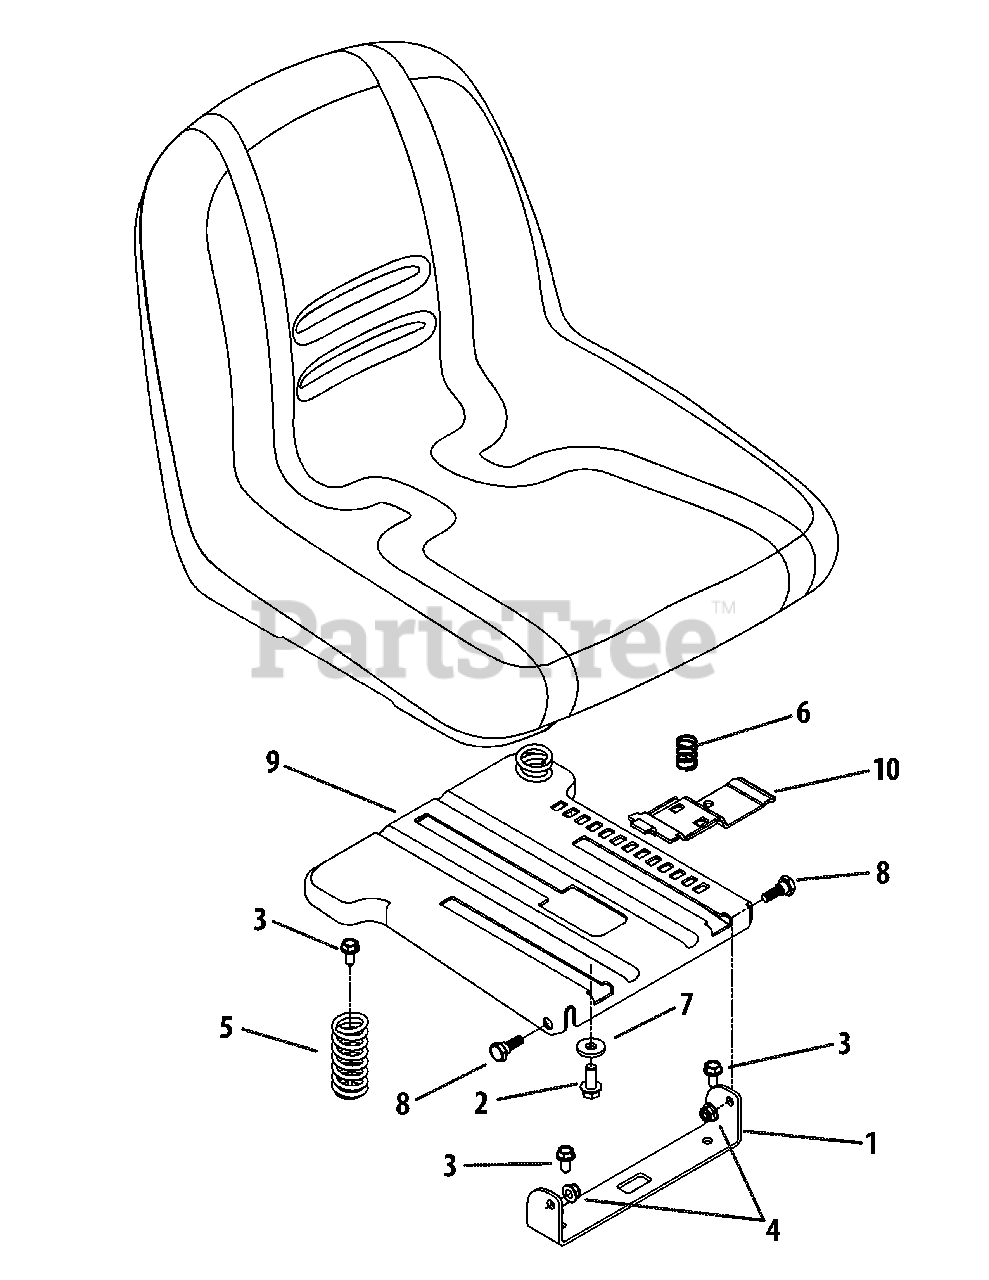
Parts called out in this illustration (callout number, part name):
2	Hex Flange Bolt, 3/8-16 x .875
3	Hex Washer Screw, 5/16-18 x .750
4	Flange Lock Nut, 5/16-18
5	Compression Spring
6	Compression Spring
7	Flat Washer, .385 x 1.0 x .135
8	Shoulder Screw, .437 x .268 x 5/16-18
9	Seat Mount Bracket
10	Seat Adjustment Lever
